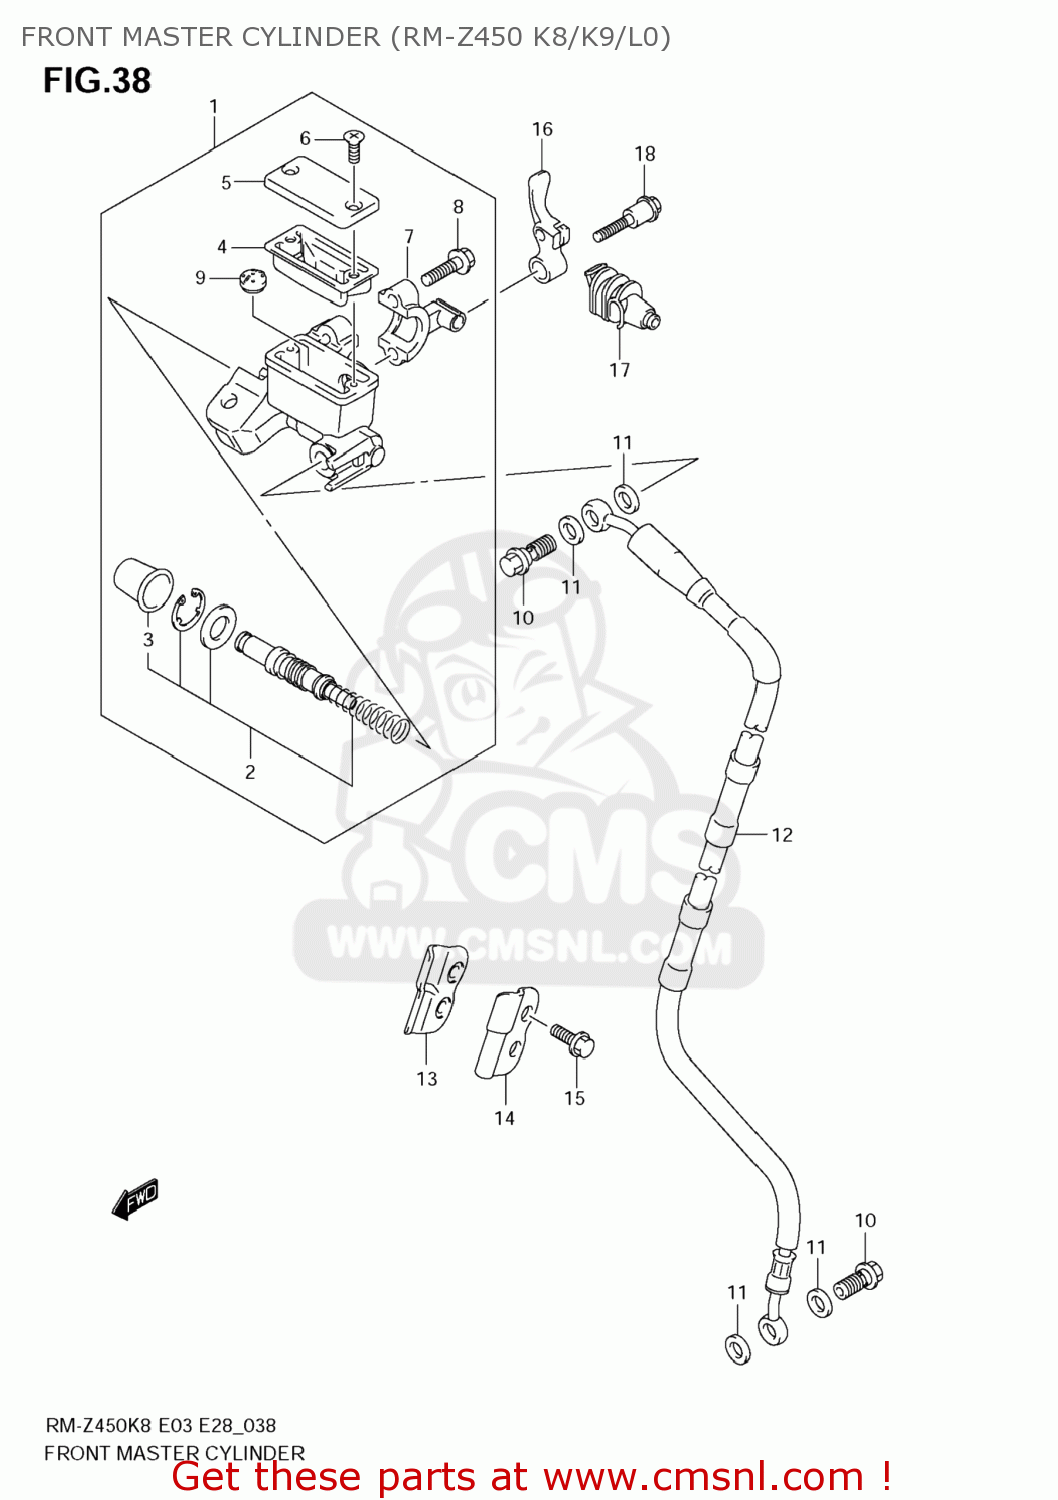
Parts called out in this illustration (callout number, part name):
1	CYLINDER ASSY,FR MASTER
2	PISTON & CUP SET
3	BOOT
4	DIAPHRAGM
5	CAP
6	SCREW
7	HOLDER
8	BOLT
9	SEPARATOR
10	BOLT UNION
11	WASHER(10X15X1.5)
12	HOSE,FR BRAKE
13	CLAMP,FR BRAKE HOSE
14	CLAMP,FR BRAKE HOSE
15	BOLT(6X16)
16	LEVER,MASTER CYLINDER HOLDER
17	COVER,MASTER CYL HOLDER LEVER
18	BOLT,MASTER CYLINDER HOLDER
